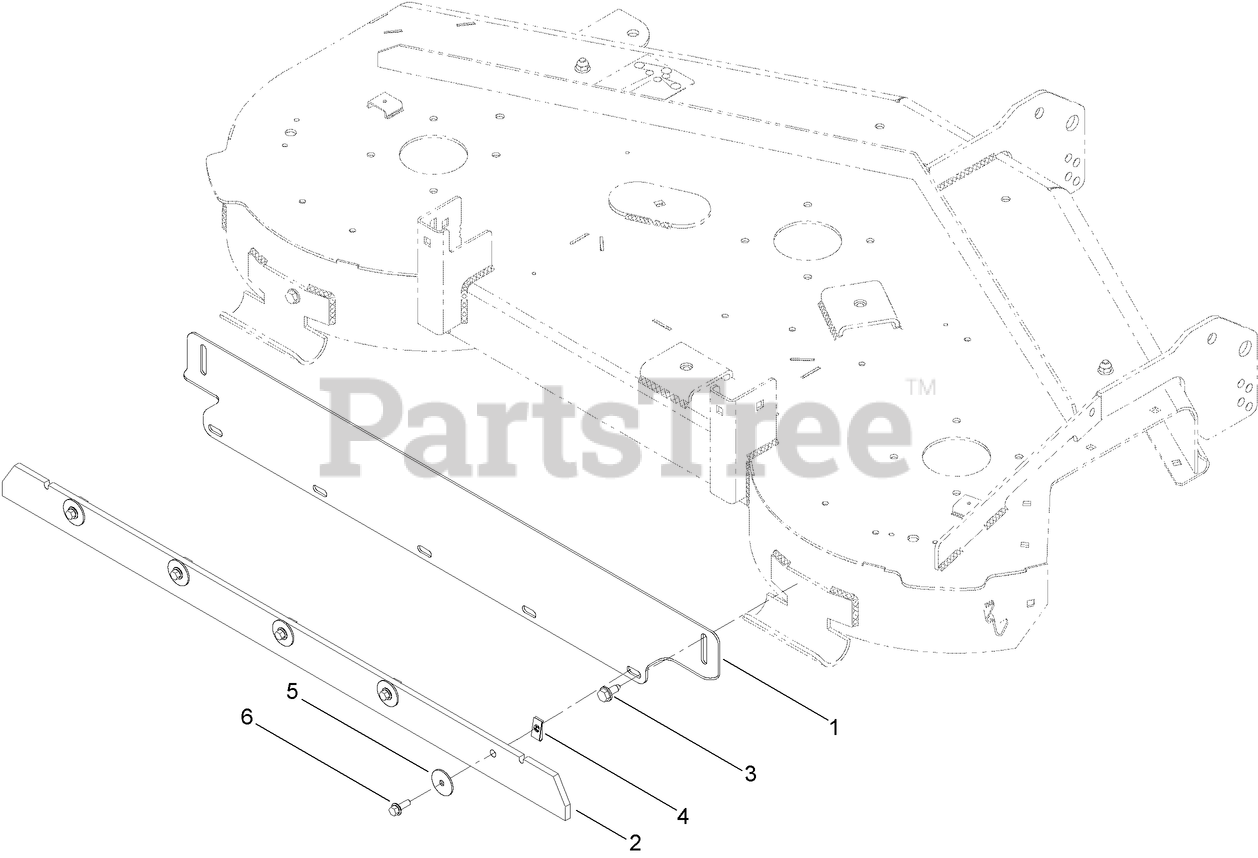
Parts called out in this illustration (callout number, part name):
1	BRACKET-STRIPING, 50IN
3	SCREW-HWHTF
4	NUT-SPEED
5	WASHER-FLAT
6	SCREW-HHF
